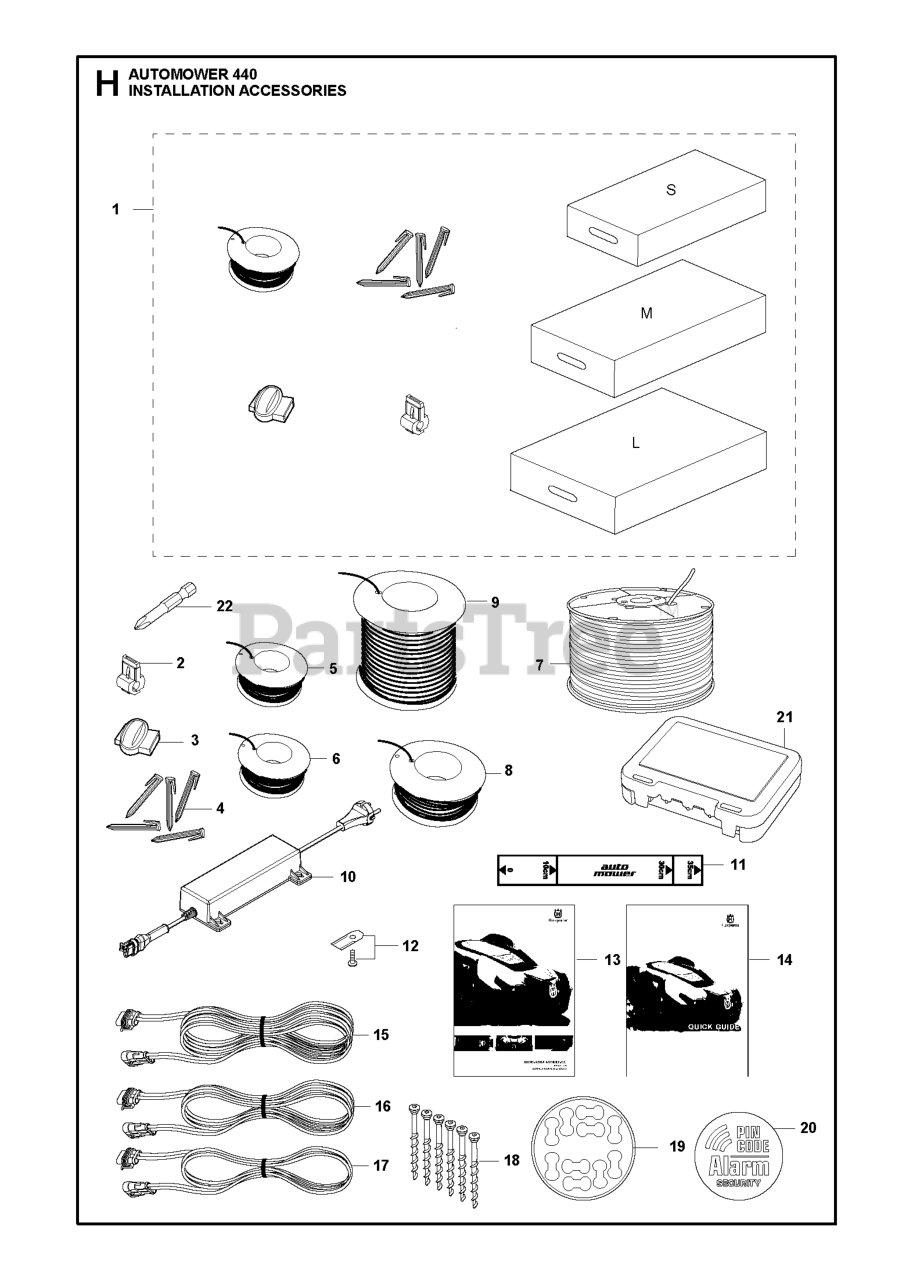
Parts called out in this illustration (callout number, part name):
1	SMALL AUTOMOWER INSTALL KIT
1	MED AUTOMOWER INSTALL KIT
1	LARGE AUTOMOWER INSTALL KIT
2	BRAKER
2	CONNECTOR 5 PCS, BLISTER
2	CONNECTOR 100 PCS
3	SPLICE KIT
3	COUPLER SPLICER, 5 PCS,
3	COUPLER SPLICER, 100 PCS
4	STAPLE 100 PCS, BLISTER
4	STAPLE 100 PCS
5	WIRE 50M STANDARD Ø2.7MM,BLIST
5	WIRE BOUNDARY 150M
5	WIRE 150M, BLISTER
6	WIRE 250M
8	WIRE 500M
9	WIRE (800M)
11	RULER / CENTIMETERS
12	HUS BLADE SET 9 PCS
12	HUS BLADE SET 45 PCS
12	HUS BLADE SET 300 PCS
15	CABLE LOW VOLTAGE CABLE P2 5-7
16	CABLE LOW VOLTAGE CABLE P2 5-7
17	CABLE LOW VOLTAGE CABLE P2 5-7
18	SCREW 3 PCS, BLISTER PACK
19	STICKER CABLE MARKERS KIT 10PC
20	LABEL SECURITY
21	CONNECTOR PROTECTION BOX
22	WRENCH BITS CHANGING ROBOTIC B
